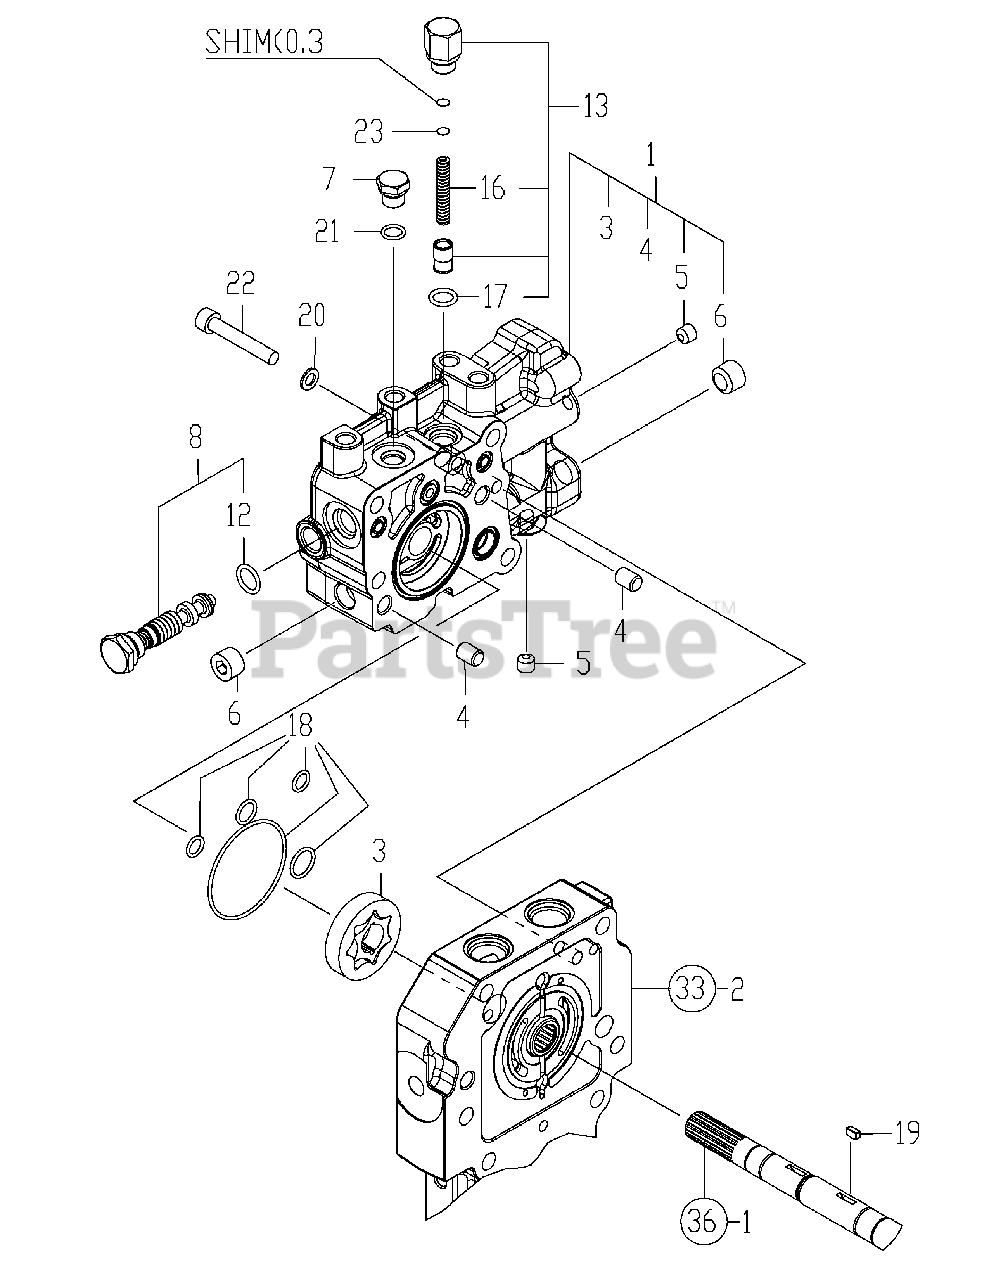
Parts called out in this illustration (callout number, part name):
1	PUMP BODY K93 CMP
7	PLUG, 1/2-20UNF
8	VALVE ASSY, REDUCING
12	PACKING, P 14.0
17	PACKING, P 12.0
20	WASHER, SEAL 8
21	PACKING, AS 905
